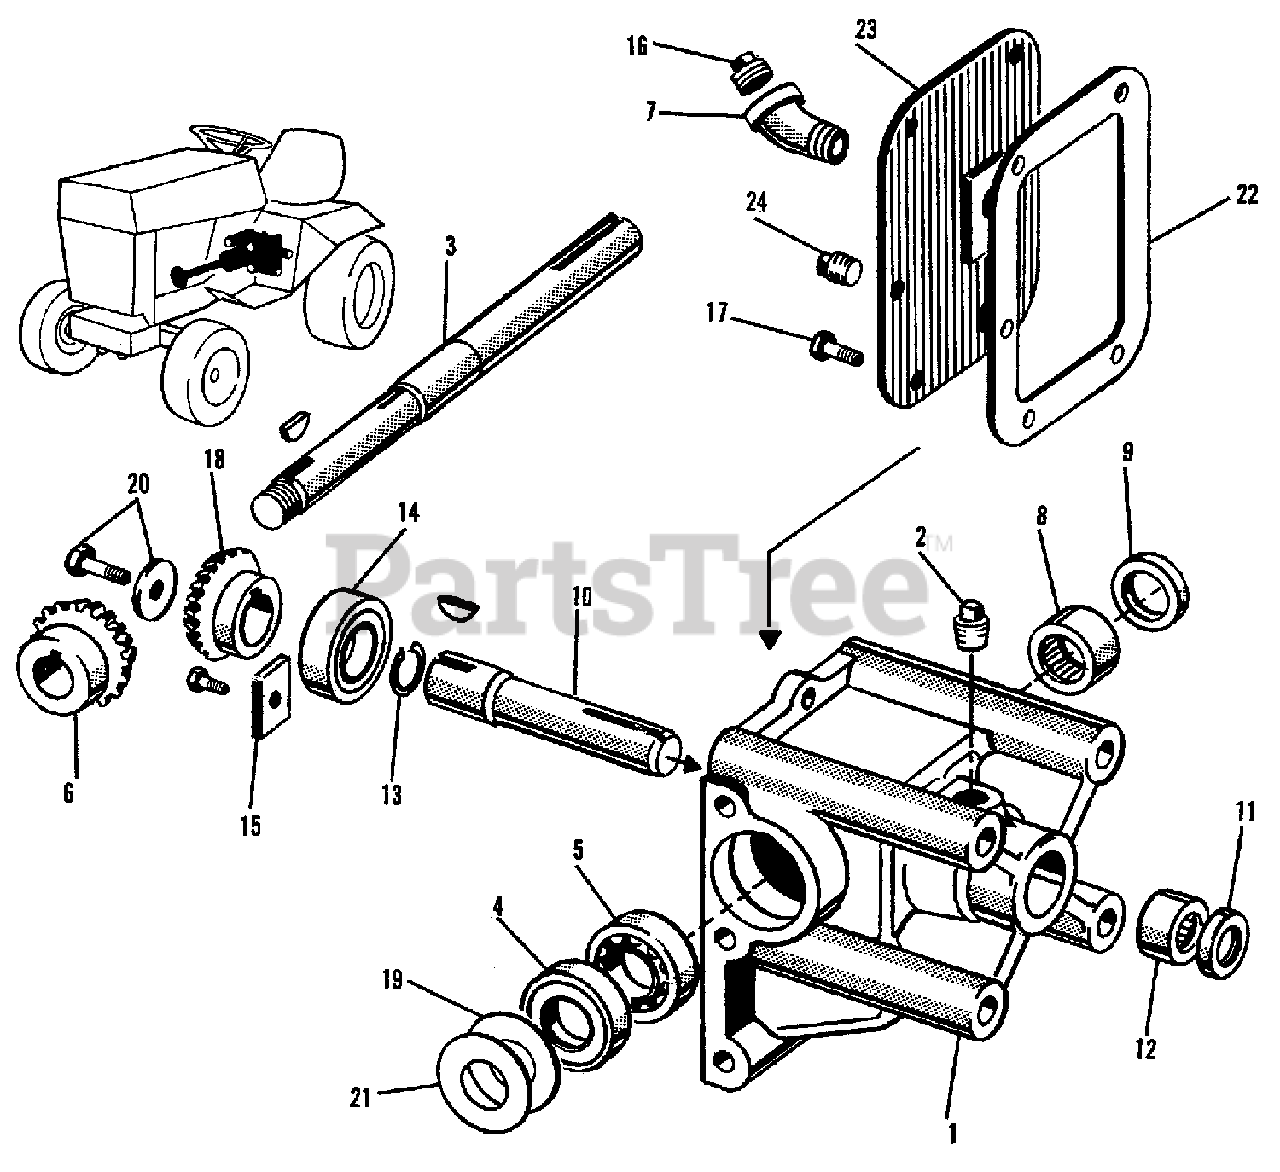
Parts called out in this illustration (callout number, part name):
1	HOUSING, Bevel Gear (Incl. Bearings)
2	PLUG, Pipe, 1/4
3	SHAFT, Driven (Used With Variable Speed Drive)
3	SHAFT, Drive (Used With Hydrostatic Drive)
3	KEY, Woodruff, 3/16 X 3/4
4	SEAL, Oil
5	BEARING, Ball
6	GEAR, Bevel, Driven
7	ELBOW, 3/8 x 90 Degrees Standard Street (Used With Variable Drive)
7	ELBOW, 3/8 x 90 Degrees Tapered Thread Brass (Used With Hydrostatic Drive)
8	BEARING, Needle
9	SEAL, Oil
10	SHAFT, Driver
10	KEY, Woodruff #9 3/16 x 3/4
11	SEAL, Oil
12	BEARING, Needle
13	RING, Retaining
14	BEARING, Ball
15	PLATE, Bridge Clamp
15	LOCKWASHER, 5/16
15	CAPSCREW, 5/16 NC x 5/8
16	PLUG, Pipe, 3/8, Standard Square Head
17	CAPSCREW, 1/4 NC x 5/8 Special
18	GEAR, Bevel, Driver
19	SHIM (Use As Required)
20	CAPSCREW, 5/16 NC x 3/4GR8
21	SHIM (Use As Required)
23	COVER, Housing
24	PLUG, Pipe, 1/4, Standard Square Head
